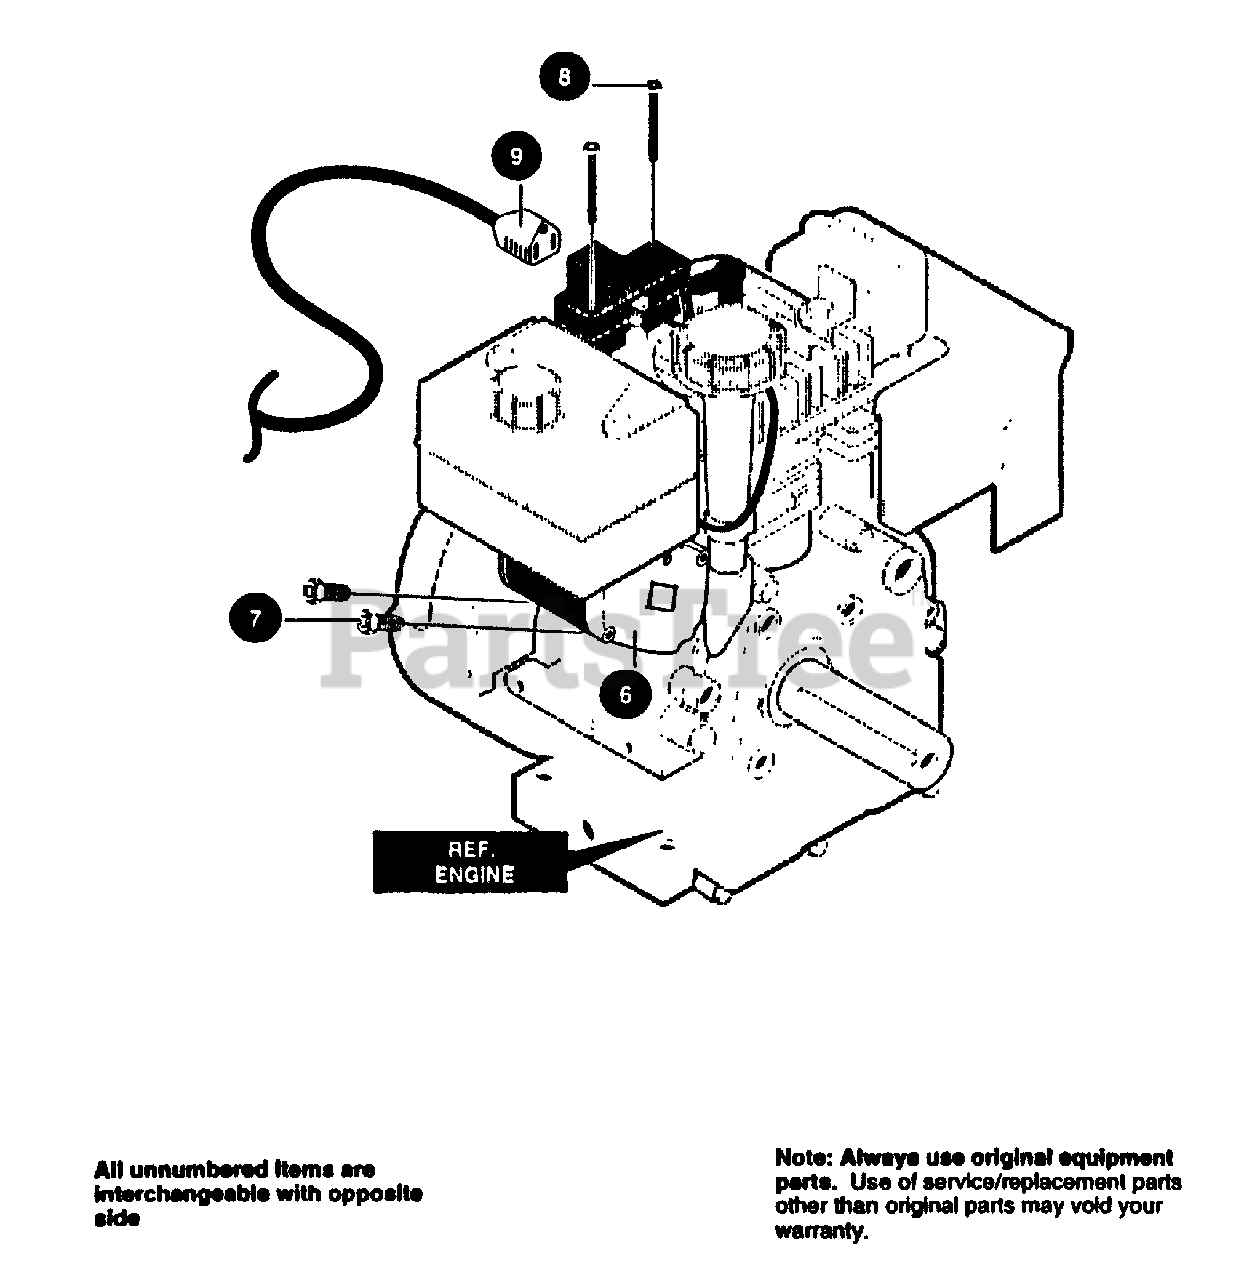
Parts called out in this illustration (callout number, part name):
6	MOTOR, STARTER
7	SCREW, 1/4-20X .50
8	SCREW, #6-32X2.50
9	CORD, STARTER
